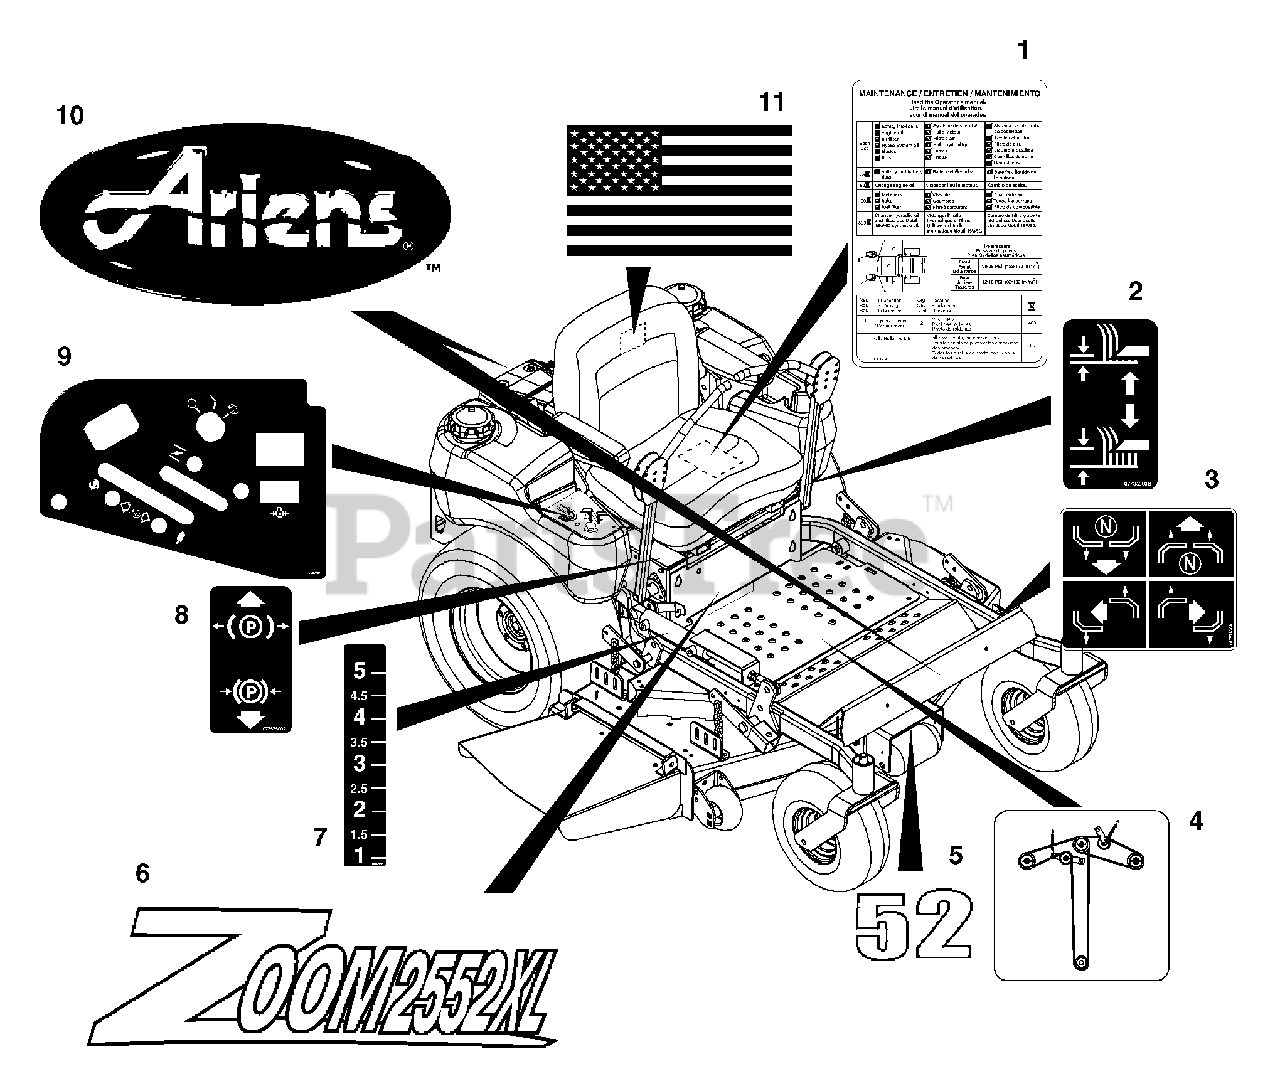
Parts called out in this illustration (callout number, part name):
1	DECAL, MAINTENANCE INSTRUCTION
2	DECAL- LIFT LEVER
3	DECAL, INSTRUCTIONAL-STEERING
4	DECAL, GRAVELY BELT DIAGRAM
5	DECAL - 52"
6	DECAL, ZOOM 2552 XL
7	DECAL, HEIGHT OF CUT
8	DECAL, PARKING BRAKE LEVER
9	DECAL CONTROL PANEL
10	DECAL, ARIENS JEWEL
11	DECAL, AMERICAN FLAG
